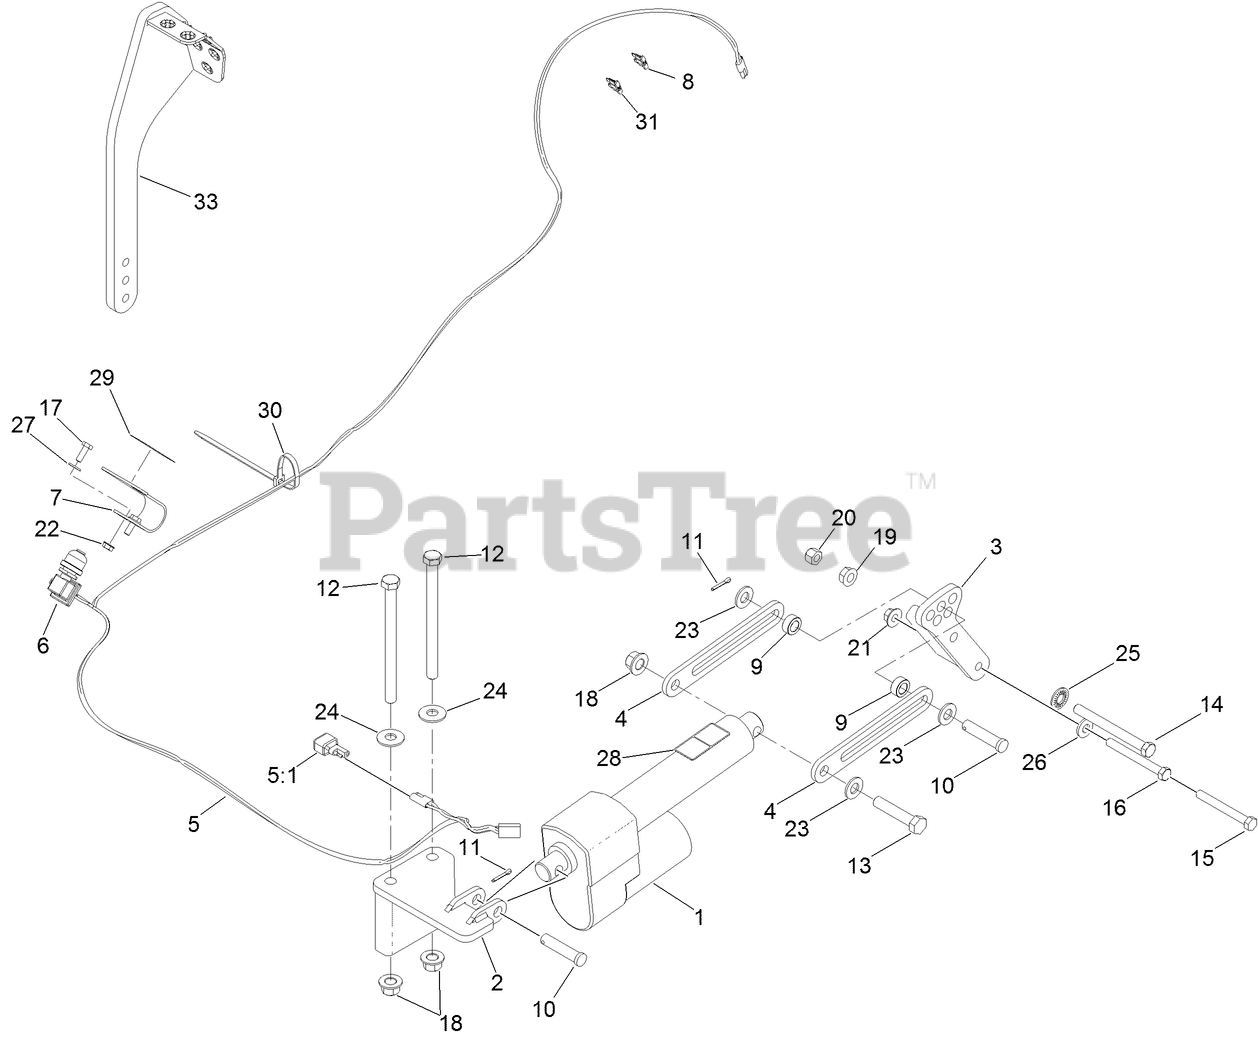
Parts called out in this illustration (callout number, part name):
1	ACTUATOR-LINEAR, DECK LIFT
2	BRACKET-LIFT, DECK
3	BRACKET-LIFT, DECK
4	PLATE-ACTUATOR
5	HARNESS-DECKLIFT, ELECTRIC
6	SWITCH-MOMENTARY
7	SPRING-LEAF, RETURN
8	FUSE-BLADE, 25 AMP
9	SPACER
10	PIN-CLEVIS
11	PIN-COTTER
12	SCREW-HH
13	SCREW-HH
14	SCREW-HH
15	SCREW-HH
16	SCREW-HH
17	SCREW-HH
18	NUT-LOCK
19	NUT-HF
20	NUT-LOCK, NI
21	NUT-FLANGE
22	NUT-HF
23	WASHER-FLAT
24	WASHER-SPRING
25	WASHER-SPRING
26	WASHER-BELLEVILLE
27	WASHER-FLAT
28	DECAL-WARNING, DO NOT STEP
29	DECAL-POWER DECK LIFT
30	TIE-PLASTIC
31	FUSE-BLADE, 30 AMP
33	LEVER-FOOT
